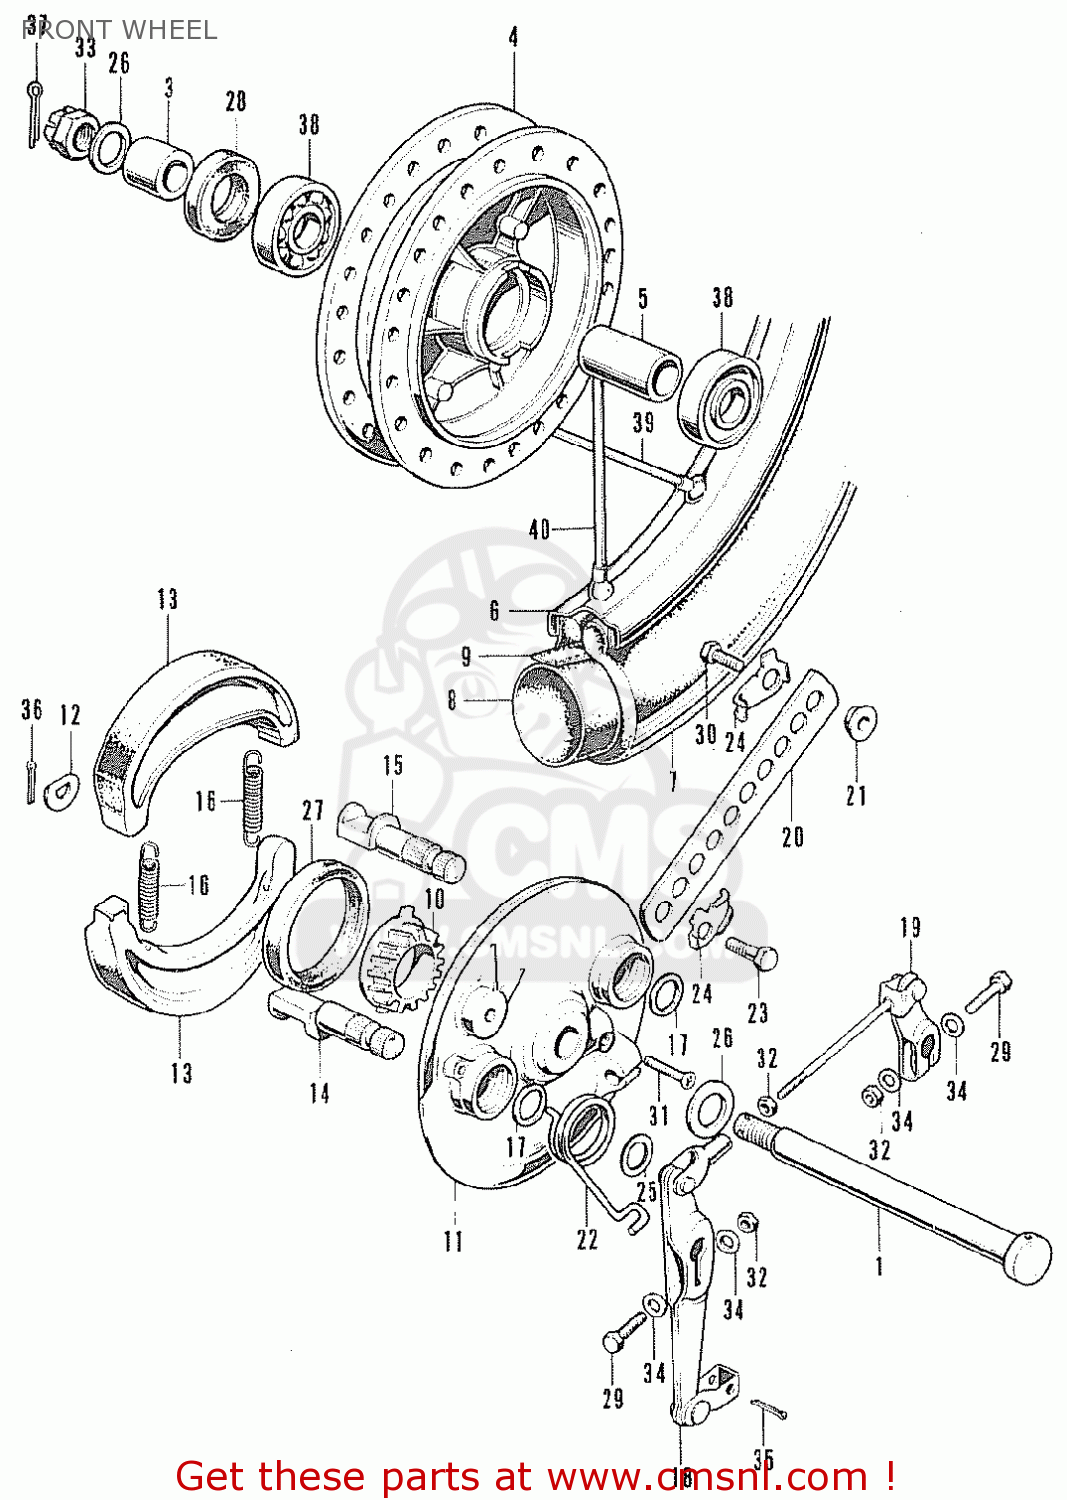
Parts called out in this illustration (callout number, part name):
1	AXLE,FRONT WHEEL
3	COLLAR,WHEEL SIDE
4	HUB,FRONT WHEEL
5	COLLAR,FRONT AXLE
6	RIM,FRONT WHEEL
7	TIRE,250-18NT-77
8	TUBE 250X18
9	FLAP 18-20
10	GEAR,SPEEDOMETER
11	PANEL,F.BRAKE
12	PIN,ANCHOR WASHER
13	SHOE,FRONT BRAKE (MCA)
14	CAM A,FRONT BRAKE
15	CAM B,FRONT BRAKE
16	SPRING,FR.BRAKE
17	DUST-SEAL, BRAKE
18	ARM A FR BRAKE
19	ARM B FR BRAKE
20	ARM,BRAKE STOPPER
21	COLLAR BRAKE ARM
22	SPRING FRT BRAKE
23	BOLT,HEX 8X28
24	WASHER,TANGUED8.2
25	WASHER,PLAIN 14MM
26	WASHER, 15.2X25
27	OIL SEAL,54667
28	OIL SEAL 26427
29	BOLT,HEX 6X32
30	BOLT,HEX 8X28
31	SCREW,FLAT,5X20
32	NUT,HEX 6MM
33	NUT,CASTLE 14MM
34	WASHER,PLAIN, 6MM
35	PIN,SPLIT, 2.0
36	PIN,SPLIT, 2.0
37	PIN COTTER 3.0MM
38	B/BRG RAD N/COM
39	SPOKE,B#9X158
40	SPOKE,9X157.5
